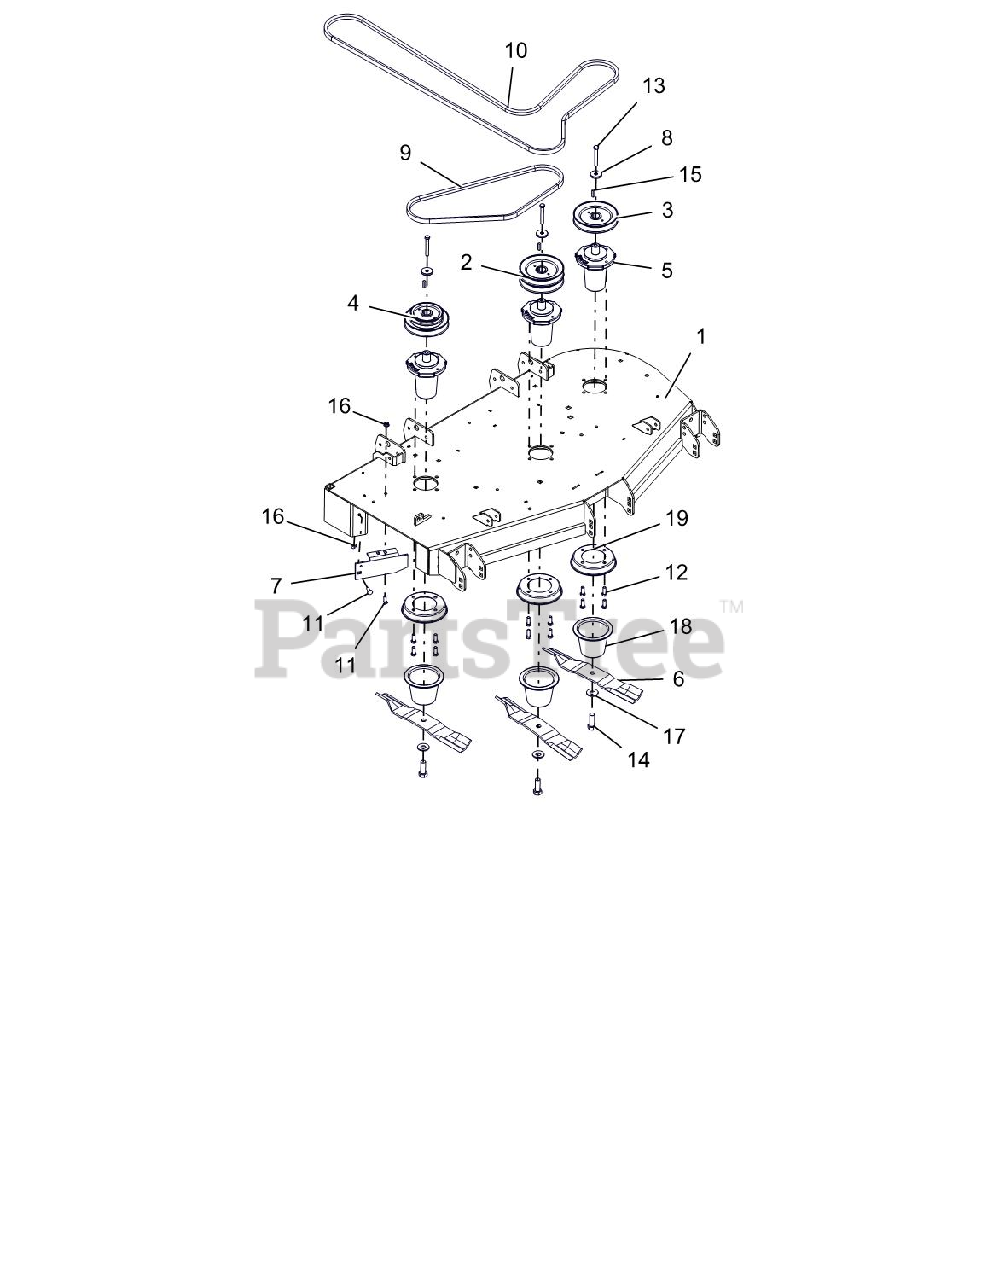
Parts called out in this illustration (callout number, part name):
1	WLDMT, PT148 SIDE DISCH DECK (RED)
2	PULLEY, DOUBLE 1.000 ID X 5.750 OD-BLACK
3	PULLEY, V - 1.000 ID X 5.750 OD
4	PULLEY, DOUBLE -1" ID X 5.75" & 4.25" OD
5	ASM, G3500 SPINDLE
6	BLADE, 16.19" MOWER (HI-LIFT)
7	BAFFLE, 44-48" SIDE DISCHARGE
8	RETAINER, SHEAVE SPINDLE
9	V-BELT, B-RAW EDGE COGGED
10	V-BELT, B RAW EDGE EPDM
11	BOLT, CARRIAGE 0.3125-18X1 GR5
12	BOLT, HEX 0.375-16X1 GR8
13	BOLT, HEX 0.375-16X2.75 GR8
14	BLT-HEX .625-18X1.75 GR8 YWZC
15	KEY-SQ .250X.250X1.00 RC 40-50
16	NUT-LK-NYL-FLG .31-18 YWZC
17	WSHR, BLVL-.63X1.625X.14
18	GUARD, SPINDLE
19	SPINDLE, GUARD TOP
